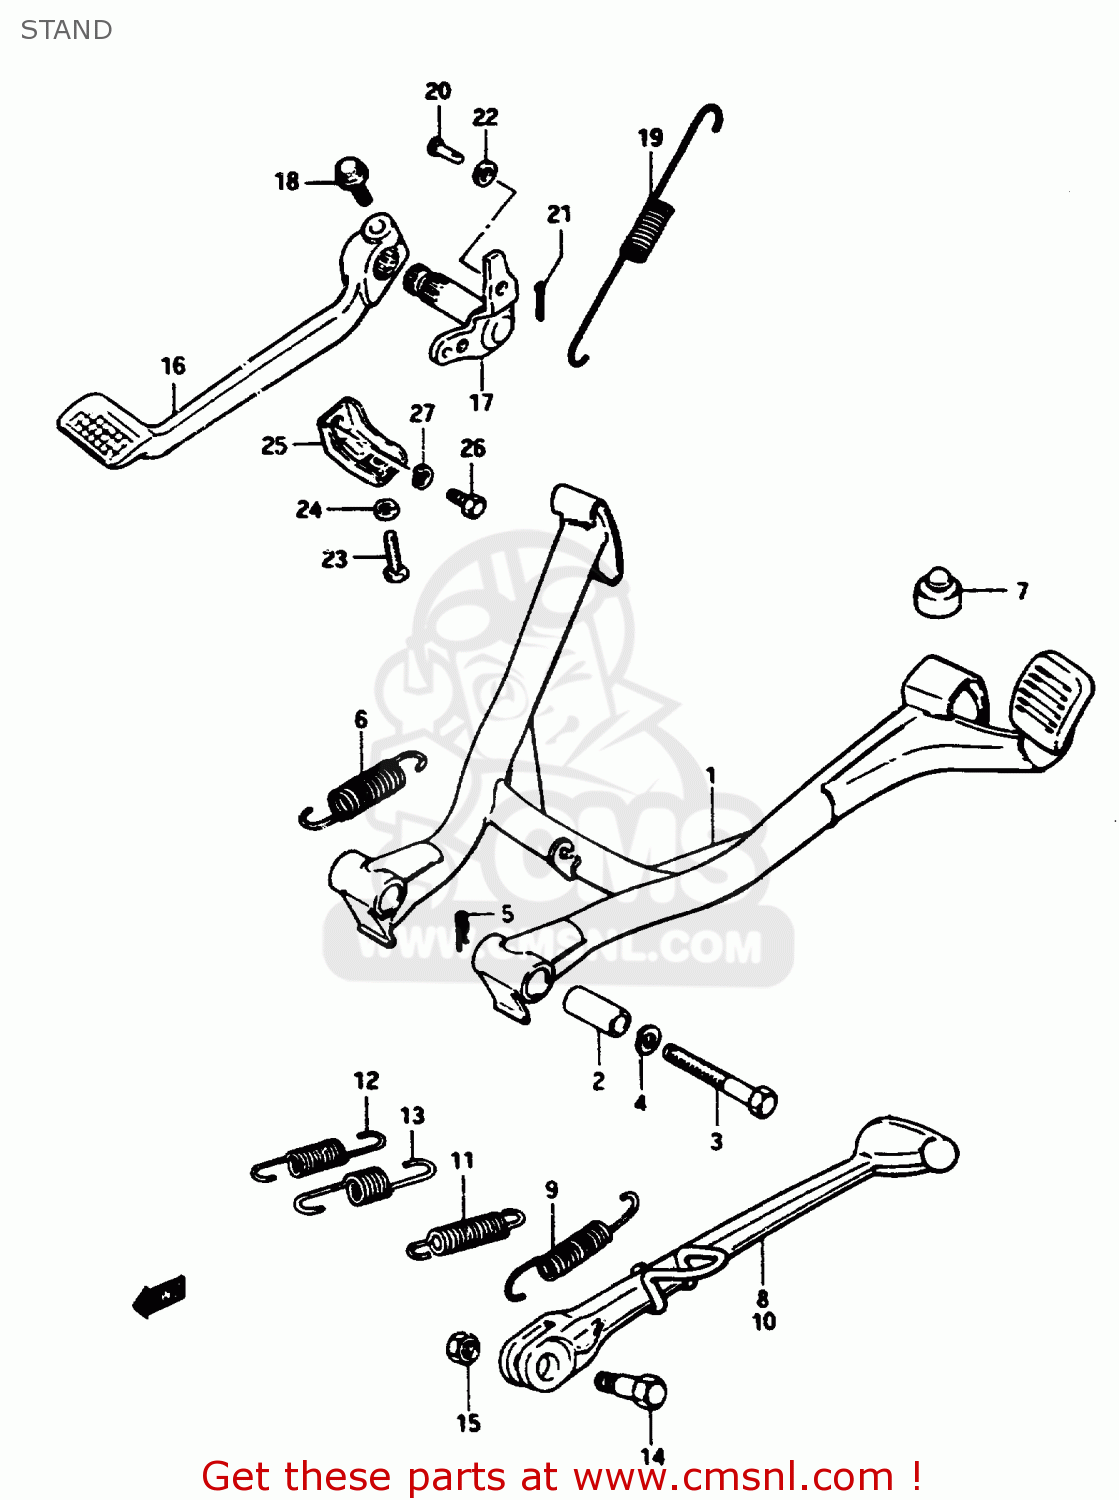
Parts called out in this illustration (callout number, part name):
1	STAND,CENTER
2	SPACER(10X16X38.8)
3	BOLT
4	WASHER,LOCK,10
5	CLIP
6	SPRING
7	CUSHION(11.5X22X20)
8	STAND,SIDE
9	SPRING
10	STAND, PROP (BLACK)
11	SPRING
12	SPRING, INNER
13	SPRING, OUTER
14	BOLT(10X32)
15	NUTM10X1.25X8
16	PEDAL,BRAKE
17	ARM,BRAKE PEDAL ROD
18	BOLT
19	SPRING
20	PIN
21	PIN
22	WASHER
23	BOLT(6X25)
24	NUT 6MM
25	BRACKET, BRAKE ADJUSTE
26	BOLT
27	WASHER,LOCK
